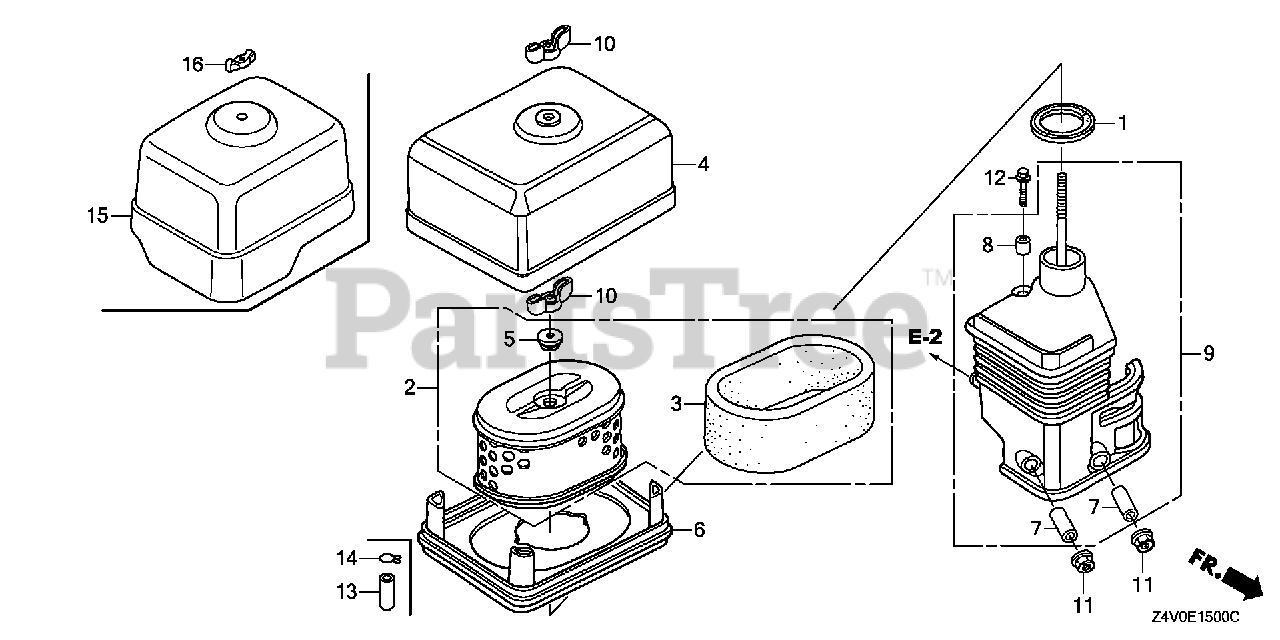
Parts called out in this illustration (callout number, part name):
1	GASKET, ELBOW
2	ELEMENT, AIR CLEANER (DUAL)
3	FILTER (OUTER)
4	COVER, AIR CLEANER (DUAL)
5	GROMMET, AIR CLEANER
6	NOSE, MUFFLER
7	COLLAR, AIR CLEANER
8	COLLAR B, AIR CLEANER
9	ELBOW, AIR CLEANER
10	NUT, TOOL BOX SETTING
11	NUT, FLANGE (6MM)
12	BOLT, FLANGE (6X20)
